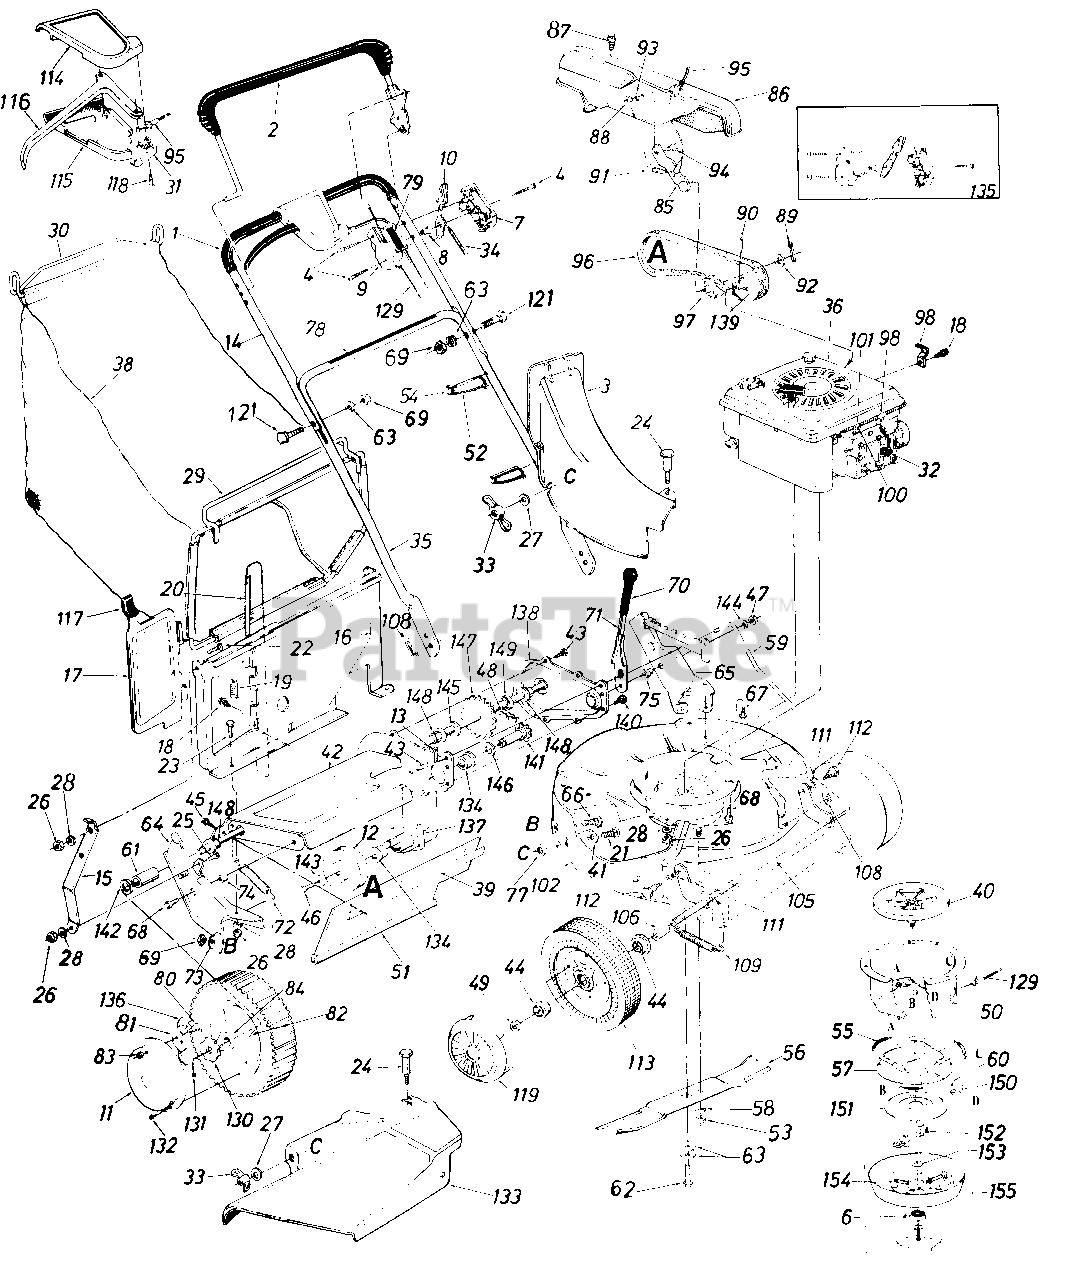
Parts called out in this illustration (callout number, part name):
2	Control Handle Ass'y.-L.H.
3	Top Discharge Chute Ass'y
4	Truss Mach. Scr. #12 x 1.50" Lg.
6	Ball Brg. .669" I.D. x 1.574"
7	Control Panel Half
8	Control Disc Pin
9	Clutch Panel Half
10	Throttle Control Lever
11	Hub Cap
12	1/2" V-Pulley
13	Cotter Pin 3132" Dia. x .75"*
14	Upper Handle-Chrome
15	Panel Support Brkt.
16	Top Catcher Panel
17	Top Door
18	Hex B-Tap Scr. #10 x .38"
19	Torsion Spring
20	Pivot Pin
21	Carriage Bolt 1/4-20 x .62"*
22	Truss Mach. Scr. 1/4-20 x .50"
23	Hex Bolt 1/4-20 x .50" Lg.
24	Shoulder Bolt .312 Dia. x .18 Lg. Special
25	Hex Bolt 1/4-20 x .62" Lg.*
26	Hex Nut 1/4-20 Thd.*
27	Fl-Wash. .280" I.D. x .620"
28	L-Wash. 1/4" I.D.*
29	Front Grass Catcher Frame
30	Grass Catcher Handle
31	S.P. Control Cover
32	Spark Plug Insulator
33	Wing Nut
34	Throttle Control Wire 58"
35	Lower Handle-Chrome
36	Engine
38	21" Top Discharge Grass Bag
39	Retaining Strip
40	Fan Adapter
41	Fl-Wash. .344" I.D. x .62"
42	Chain-Axle Ass'y.
43	Hex B-Tap Scr. 1/4" x .38" Lg.
44	Flange Ball Bearing 1/2" I.D.
45	Hex AB-Tap Scr. 1/4 x .62"
46	Hex Wash. TT-Tap Scr. 1/4-20
47	Hex Patch L-Nut 3/8-24 Thd.
48	#48 Chain .500" Pitch x .30 Links
49	Hex L-Nut 1/2-20 Thd.
50	Clutch Housing
51	Rear Flap 3.75" x 17.30" Lg.
52	Cable Tie
53	Hex Nut 3/8-24 Thd. (Grade 8)
54	Cable Anchor
55	Extension Spring .35" O.D. x 1.75" Lg.
56	21" Blade
57	Brake Cup Cone
58	L-Wash. 3/8" I.D.*
59	Height Adj. Rod 19.42" Lg.
60	Steel Ball .500" Dia.
61	Spacer .51" I.D. x .69" O.D. x.69" Lg.
62	Hex Cent. L-Bolt 3/8-24 x 2.0" Lg. (Grade 8)
63	Bell-Wash. 3/8" I.D.
64	R.H. Handle Wheel Brkt. Ass'y.
65	L.H. Handle Wheel Brkt. Ass'y.
66	Carriage Bolt 5/16-18 x .62"*
67	Hex Wash. Hd. B-Tap Scr. 5/16-1 8
68	Hex Wash. Hd. TT-Tap Scr. 3/8-16
69	Hex Nut 5/16-18 Thd.
71	Height Adj. Lever
72	Extension Spring .50" O.D. x 3.80" Lg.
73	Bell-Wash. .345" I.D. x .88"
74	Spacer .385" I.D. x .502" O.D. x .270" Lg.
75	Shld. Spacer .500" Dia. x . 100
77	Bolt Retainer 1/4 x .50" O.D.
78	Instruction Label
79	Control Label
80	Shld. Scr. .342" Dia. x .268
81	Pawl
82	Wheel Ass'y. Comp.-Rear 8 x 1 .75
83	Hex Ins. L-Nut 1/4-20 Thd.
84	Flange Ball Bearing 1/2" I.D.
85	Belt Idler Bracket Ass'y.
86	Belt Cover
87	Hex Wash. S-Tap Scr. 1/4-20 x.50" Lg.
88	Hex Nut 1/4-20 Thd.
89	Cotter Pin 1/8" Dia. x 1.00" Lg.*
90	Spring Pin Spir. 3/16" Dia. x 1.00" Lg.
91	Extension Spring .33" O.D. x 1.12" Lg.
92	Fl-Wash. .531" I.D. x .930" O.D. x .050
93	L-Wash. 1/4" I.D.
94	Shld. Bolt .375" Dia. x .181
95	S.P. Cable x 53.0" Lg.
96	"V"-Belt 1/2" x 32.0" Lg.
97	Fl-Idler Plastic 1.62" Dia.
98	Casing Clamp
100	Hex B-Tap Scr. #10 x .62"
101	Casing Clamp
106	Sleeve .526" I.D. x .690" O.D. x .880" Lg.
108	Intern. Cotter Pin 5/16" Dia.
109	Extension Spring .50" O.D. x 3.20" Lq.
111	Intern. L-Wash 3/8 I.D.
112	Shld Bolt. 623" Dia. x .425
113	Front-Wheel Ass'y. Comp. 7 x 1.50
114	Self-Propelled Control Cover
115	Self-Propelled Control Cover
116	Control Lever
117	Door Grip
118	Fl-"C"-Sunk Hd. Tap Scr. #10 x .75" Lg.
119	Hub Cap-Plastic-Black
121	Curved Carr. Bolt 5/16-18 x 1.38" Lg.
129	Blade Brake/Clutch Cable-46" Lg.
130	Ratchet Wheel 1.62" O.D.
131	Cotter Pin 1/8" Dia. x 1.00" Lg.*
132	Pan Hd. Tap Scr. #12 x .50" Lg.
133	Side Chute Deflector Ass'y.
134	Flange Bushing
135	Kit-Control Housing Comp.
136	Spring-Nylon
137	Bearing Hub Flange Ass'y.
138	Chain Cover
139	Engine Pulley 1/2"
140	Hex Wash. S-Tap Scr. 1/4-20 x.50" Lg.
141	Sprocket-Shaft Ass'y.
142	Fl-Wash. .531" I.D. x .93" O.D.
143	Bell-Wash. .265" I.D. x .75"O.D.
144	Fl-Wash. .385" I.D. x .87"O.D.
145	Fl-Wash. .51" I.D. x 1.0"O.D.
146	Fl-Wash. .62" I.D. x 1.12"O.D.
147	Rear Shaft Ass'y. 22.05" Lg.
148	Hex Flange Bearing .506" I.D. Plastic
149	Spacer .510" I.D. x 1.00" O.D. x .210" Lg.
150	Ball Block
151	Clutching Cone
152	Hex Tap L-Scr. 1/4-20 x .75" Lg.
153	Fl-Wash. .690" I.D. x 1.060" O.D.
154	Compression Spring .35" O.D. x 2.00" Lg.
155	Clutch Blade Housing Ass'y.
